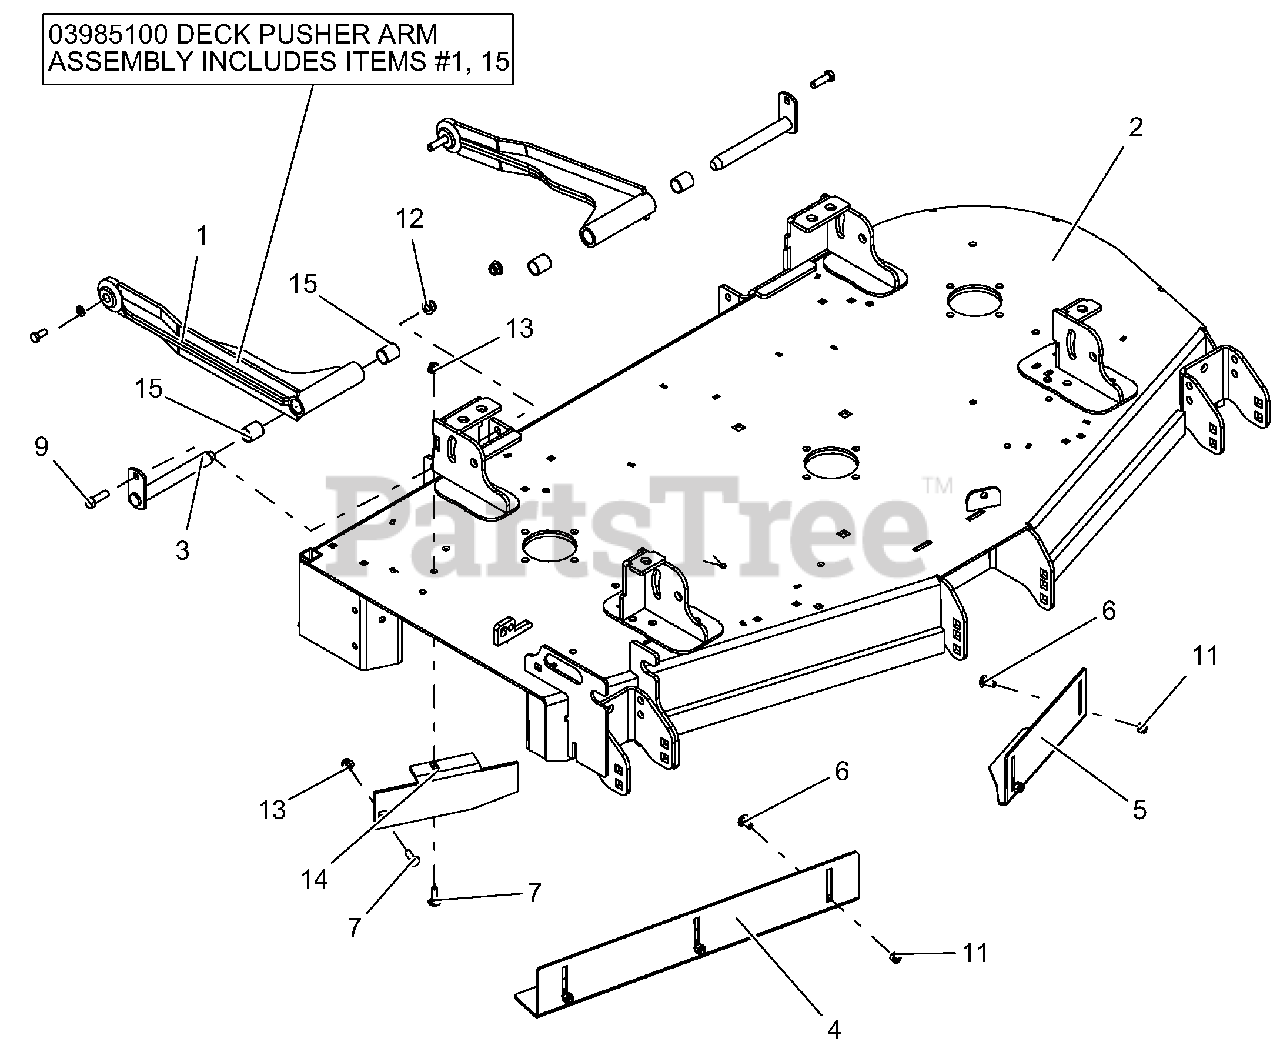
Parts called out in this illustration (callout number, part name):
1	WMT, DECK STABILIZER ARM-BLACK
2	WLDMT, 52" PT200 SIDE DISCHARGE DECK-RED
3	WLDMT, MOWER MTG. PIN
4	BAFFLE, 52" RH VACUUM-BLACK
5	BAFFLE, 52" LH VACUUM-BLACK
6	BLT-RDHDSQNK .31-18X.75 G5 YWZC
7	BLT-RDHDSQSHNK .31-18X1.00 G5 Y
9	BLT-HEX .38-16X1.25 GR5 YWZC
11	NUT-LK-NYL .312-18 YWZC
12	NUT-LK-NYL-FLG .38-16 YWZC
13	NUT-LK-NYL-FLG .31-18 YWZC
14	BAFFLE, 52" DISCHARGE-RED
15	BRG, .75 X .875 X 1.00
